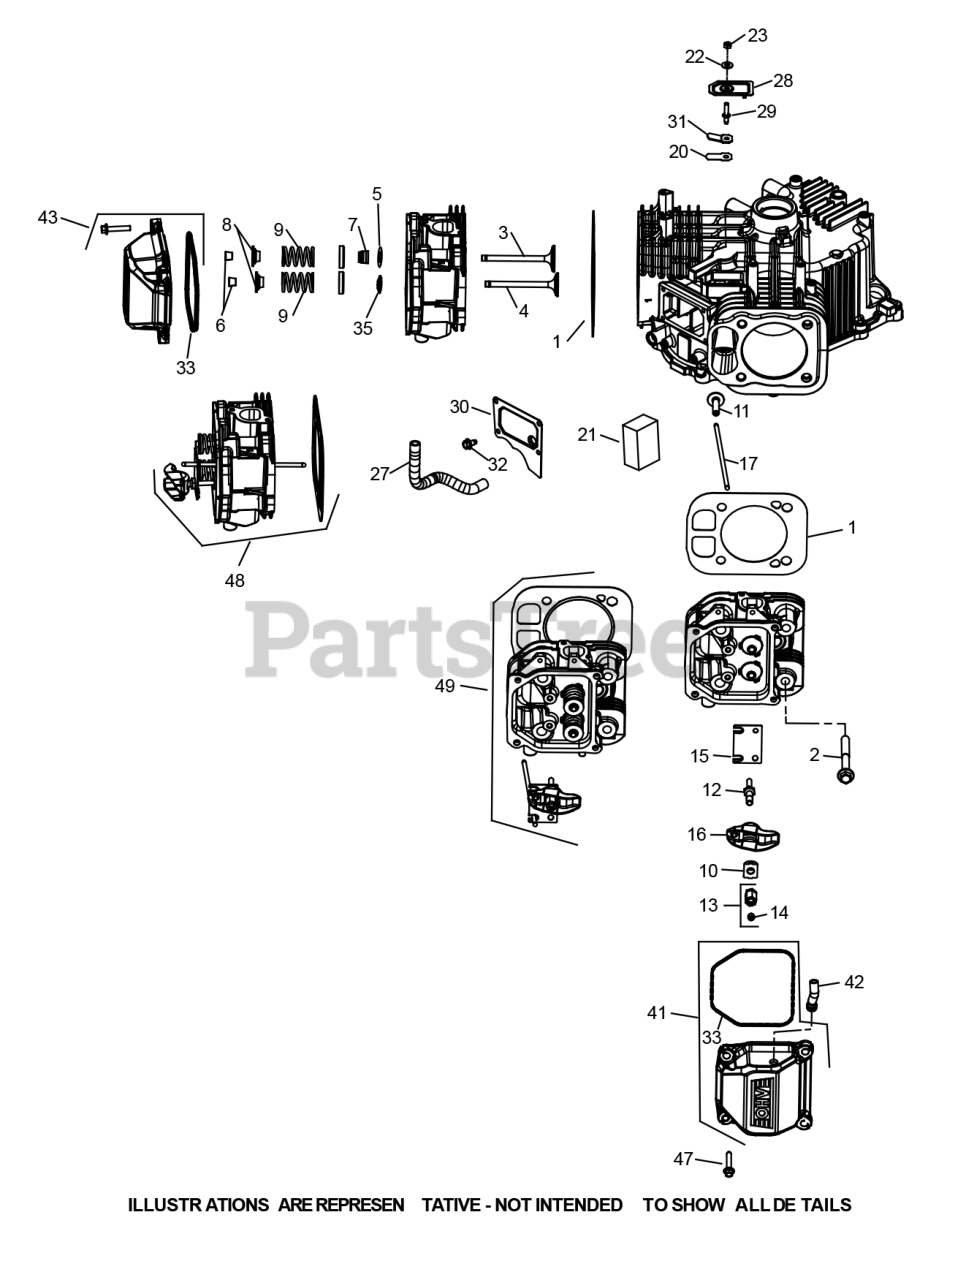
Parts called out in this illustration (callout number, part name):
1	GASKET KIT-CYL HEA
2	SCREW-HEX FLG M10X1.5-6X90
3	INTAKE VALVE .25
4	EXHAUST VALVE
4	EXHAUST VALVE .25
6	KIT-RETAINER
7	VALVE STEM SEAL
8	VALVE CAP SPRING
10	PIVOT- ROCKER ARM
11	TAPPET-PUSH ROD
13	NUT ASSEMBLY-ROCKER
20	BREATHER REED
21	BREATHER FILTER
22	SEALING WASHER
27	BREATHER HOSE
28	COVER-BREATHER REED
29	STUD-BRETHR REED C
30	COVER-BREATHER FILTE
31	RETAINER-BREATHER
33	O-RING VLV CVR
35	VALVE GUIDE RETAINER
41	KIT-ROCKER COVER
42	HOSE KIT-FUEL PUMP
43	COVER KIT-ROCKER
47	SCREW-HEX FLANGE M6x31.625
48	CYLINDER HEAD #1
49	CYLINDER HEAD #2
